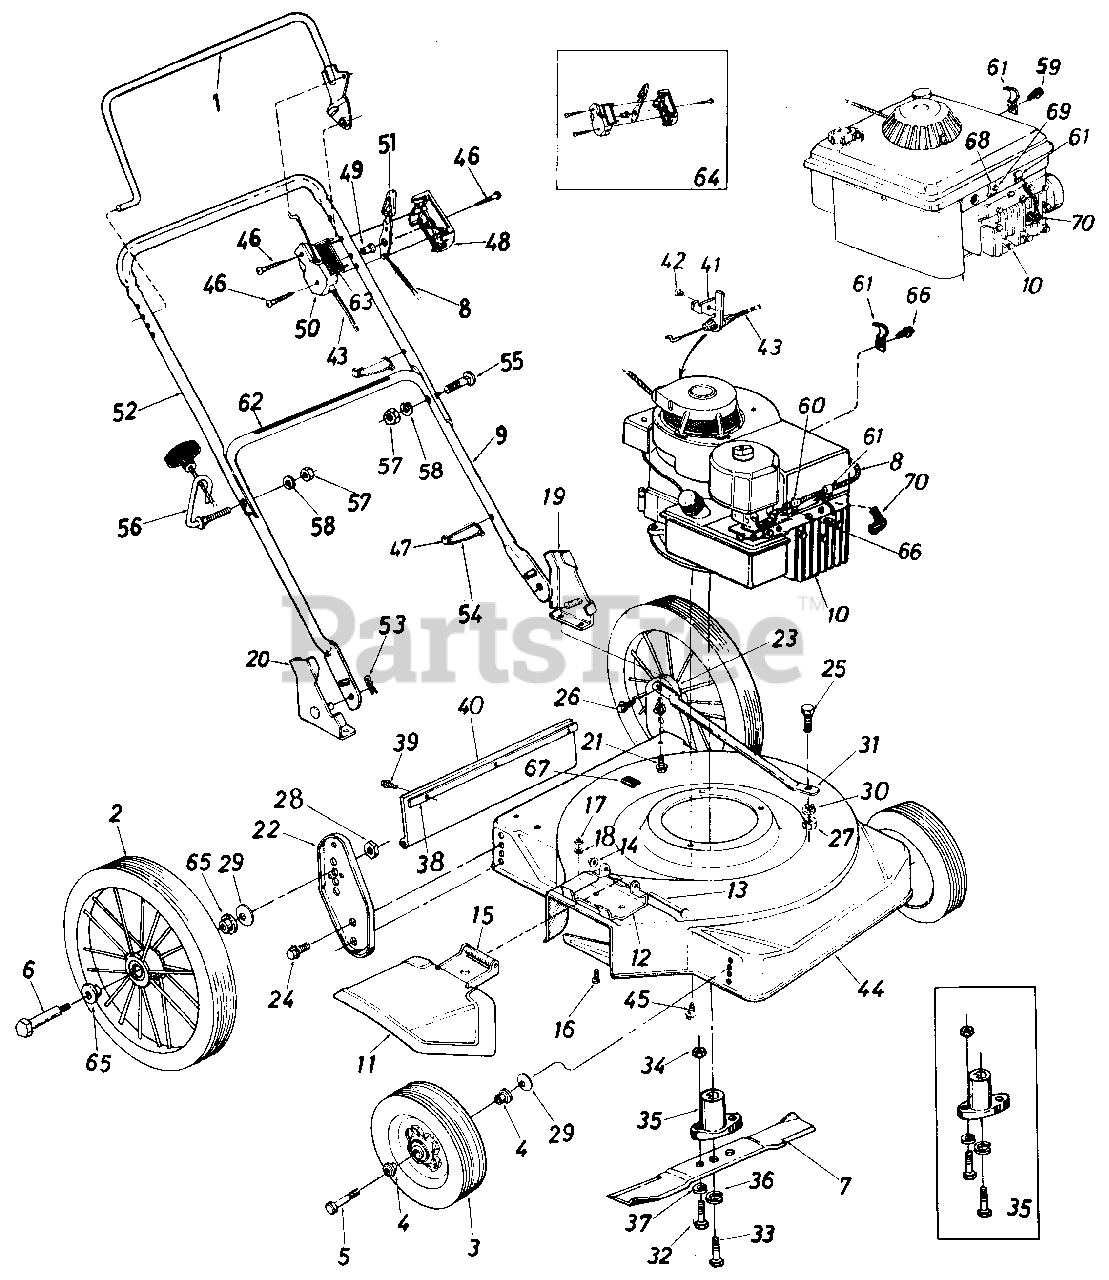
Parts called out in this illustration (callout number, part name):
1	Control Handle Ass'y.-L.H.
2	Rear Wheel Ass'y.-Comp. 14.0 x 1.75
4	Bearing
5	Axle Bolt-Front
6	Shoulder Bolt .50" Dia. x 2.62
7	22" Blade
8	Throttle Wire-58" Lg.
9	Lower Handle (Chrome)
10	Engine
11	Chute Deflector Ass'y. Comp.
12	Adapter Plate
13	Pivot Pin
14	Push Nut 1/4" Rod
15	Torsion Spring
16	Hex Bolt 1/4-20 x .50" Lg.*
17	Hex Nut 1/4-20 Thd.*
18	L-Wash. 1/4" I.D.*
19	Handle Mount Brkt.-L.H.
20	Handle Mount Brkt.-R.H.
21	Hex Wash. Hd. "B" Tap Scr. 5/16-18 x .50" Lg.
22	Extension Brkt.-R.H.
23	Extension Brkt.-L.H.
24	Hex Sems Bolt 3/8-16 x .62"
25	Hex Bolt 1/4-20 x .62" Lg.*
26	Hex Wash. Hd. "B" Tap Scr. 5/16-18 x .50" Lg.
27	Hex Nut 1/4-20 Thd.*
28	Oval Nut 3/8-16 Thd.
29	Bell-Wash. .400" I.D. x .88"
30	L-Wash. 1/4" I.D.*
31	Stabilizing Strut
32	Hex Bolt 5/16-24 x 1.00" Lg. (Grade 5)
33	Hex Bolt 3/8-24 x 2.25" Lg. (Grade 5)
34	Hex Nut 5/16-24 Thd.*
35	Blade Adapter Kit
36	L-Wash. 3/8" I.D.-H.D.
37	L-Wash. 5/16" I.D.*
38	Retaining Strip
39	Hex Wash. Hd. "AB"-Tap Scr. 1/4" x .62" Lg.
40	Rear Flap Ass'y.
41	Cable Bracket
42	Pop Rivet .156 Dia. x .379
43	Control Cable-43"
44	22" Deck Ass'y.
45	Hex Wash. Hd. TT-Tap Scr. 3/8-16 x 1.00" Lg.
46	Truss Mach. "B"-Tap Scr. #12 x 1.50" Lg.
47	Cable Anchor
48	Control Panel Half
49	Control Disc Pin
50	Clutch Panel Half
51	Throttle Control Lever
52	Upper Handle (Chrome)
53	Intern. Cot. Pin 5/16" Dia.
54	Cable Tie
55	Curved Carriage Bolt 5/16-18 x 1.38" Lg.
56	Rope Guide Bolt
57	Hex Nut 5/16-18 Thd.*
58	L-Wash. 5/16" I.D.*
59	Hex B-Tap Scr. #10 x .38" Lg.
60	Casing Clamp
61	Casing Clamp
62	Instruction Label-Handle
63	Control Label-Throttle
64	Control Housing Comp.
65	Flange Bearing
66	Hex Wash. Hd. AB-Tap Scr. #8 x .38" Lg.
67	Plastic Plug
68	Casing Clamp
69	Hex B-Tap Scr. #10 x .62" Lg.
70	Spark Plug Boot
